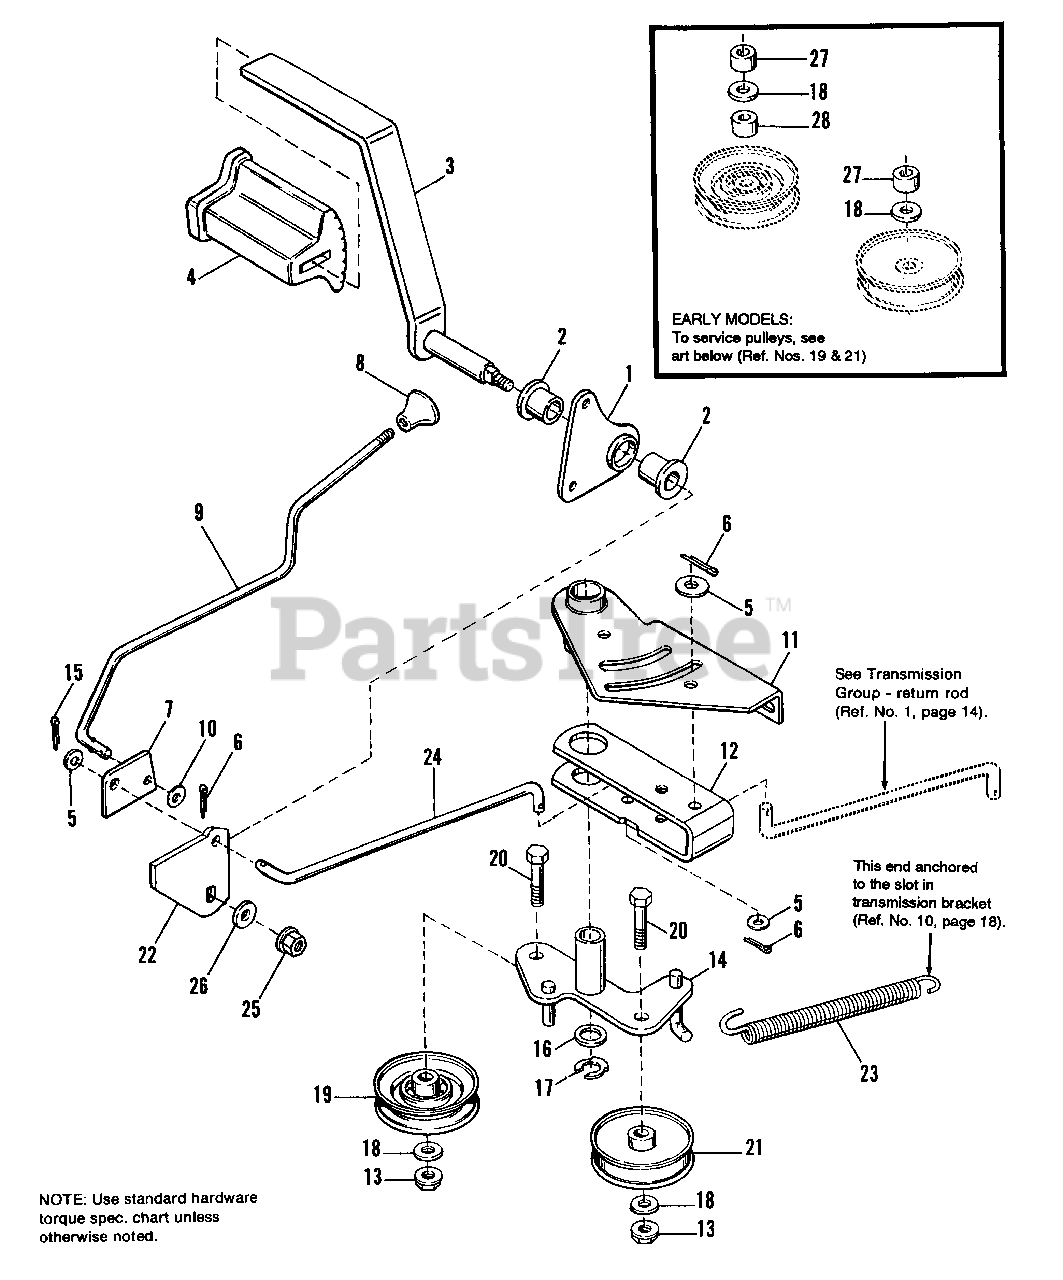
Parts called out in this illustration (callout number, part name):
2	BUSHING, Plastic
3	BRAKE PEDAL ASSY.
4	PAD, Foot Pedal
5	WASHER, Plain, 11/32
6	COTTER PIN
7	CAM, Parking Brake
8	KNOB, Plastic
9	ROD, Parking Brake
10	WASHER, Plain, 9/32
11	ACTUATOR ASSY.
12	LEVER, Clutch
13	NUT, Flange Whizlock, 3/8-16
14	PIVOT ASSY., Idler
15	COTTER PIN
16	WASHER, 5/8
17	KLIPRING, 5/8
18	WASHER, Plain, 13/32
19	PULLEY, V, 3 OD
20	CAPSCREW, 3/8-16 x 1-3/4
21	PULLEY, Idler, 2-47/64 OD
22	ARM, Foot Pedal
23	SPRING, Drive
24	ROD, Clutch, 5/16 Dia.
25	NUT, Hex ESNA, 3/8-16
26	WASHER
